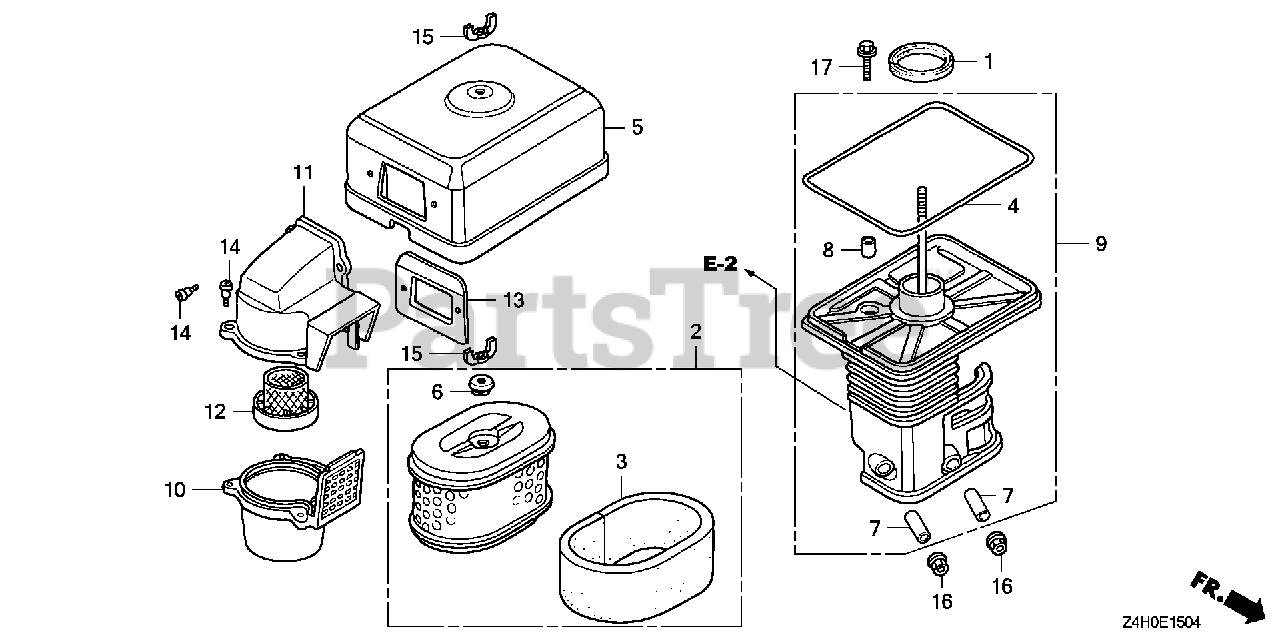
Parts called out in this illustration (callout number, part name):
1	GASKET, ELBOW
2	ELEMENT, AIR CLEANER (DUAL)
3	FILTER (OUTER)
4	GASKET, AIR CLEANER COVER
5	COVER, AIR CLEANER (CYCLONE)
6	GROMMET, AIR CLEANER
7	COLLAR, AIR CLEANER
8	COLLAR B, AIR CLEANER
9	ELBOW, AIR CLEANER
10	CASE, PRE AIR CLEANER
11	CAP, PRE AIR CLEANER
12	GUIDE, PRE AIR CLEANER
13	PLATE, PRE AIR CLEANER
14	BOLT, SPLASH GUARD
15	NUT, TOOL BOX SETTING
16	NUT, FLANGE (6MM)
17	BOLT, FLANGE (6X20)
